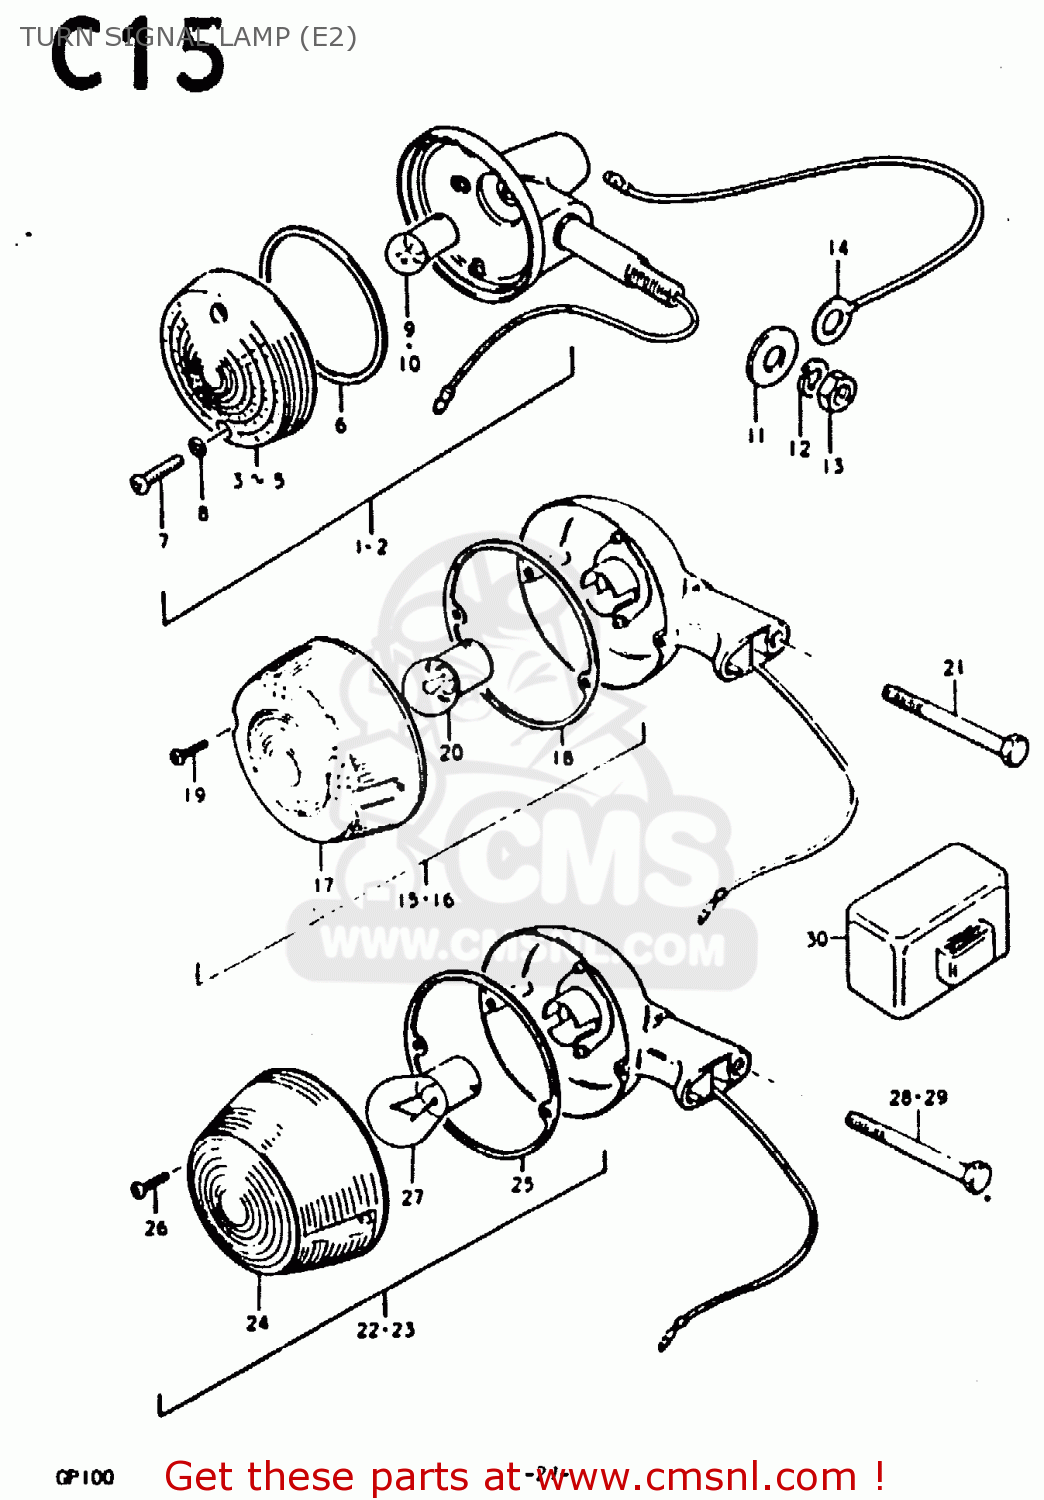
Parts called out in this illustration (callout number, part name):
1	LAMP ASSY, FRONT TURN SIGNAL
2	LAMP ASSY, REAR TURN SIGNAL
4	LENS
5	LENS
6	GASKET (NAS)
7	SCREW
8	GASKET (NAS)
10	BULB (6V,18W)
11	WASHER
12	LOCK WASHER
13	NUT
14	LEAD WIRE,EARTH
30	RELAY,TURN SIGNAL
